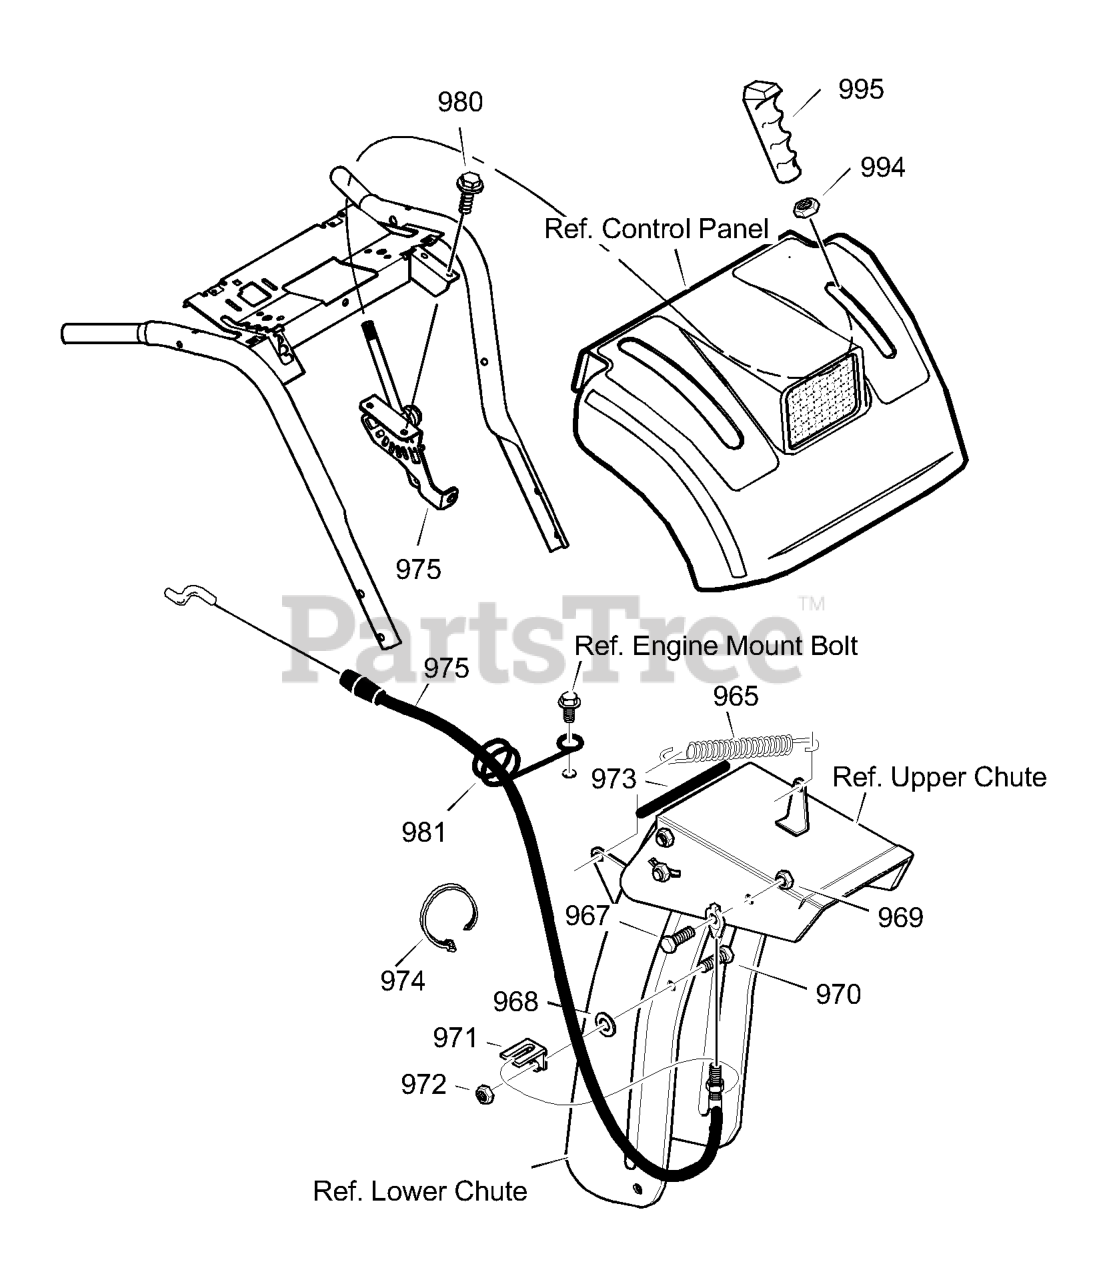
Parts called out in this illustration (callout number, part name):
965	TENSION SPRING
967	BOLT, 1/4-20 x .50
968	FLATWASHER
969	NUT, 1/4-20
970	SCREW, 1/4-20 x .38
971	BRACKET, CABLE CHUTE
972	NUT, 5/16-18
973	TRIM STRIP, GREY
974	TIE, CABLE
975	ASSY, CHUTE DEF. CONTROL
980	SCREW, 5/16-18 x 0.75
981	WIRE FORM, REMOTE CHUTE CABLE
994	NUT, 3/8-16
995	KNOB, SHIFT (BLACK)
